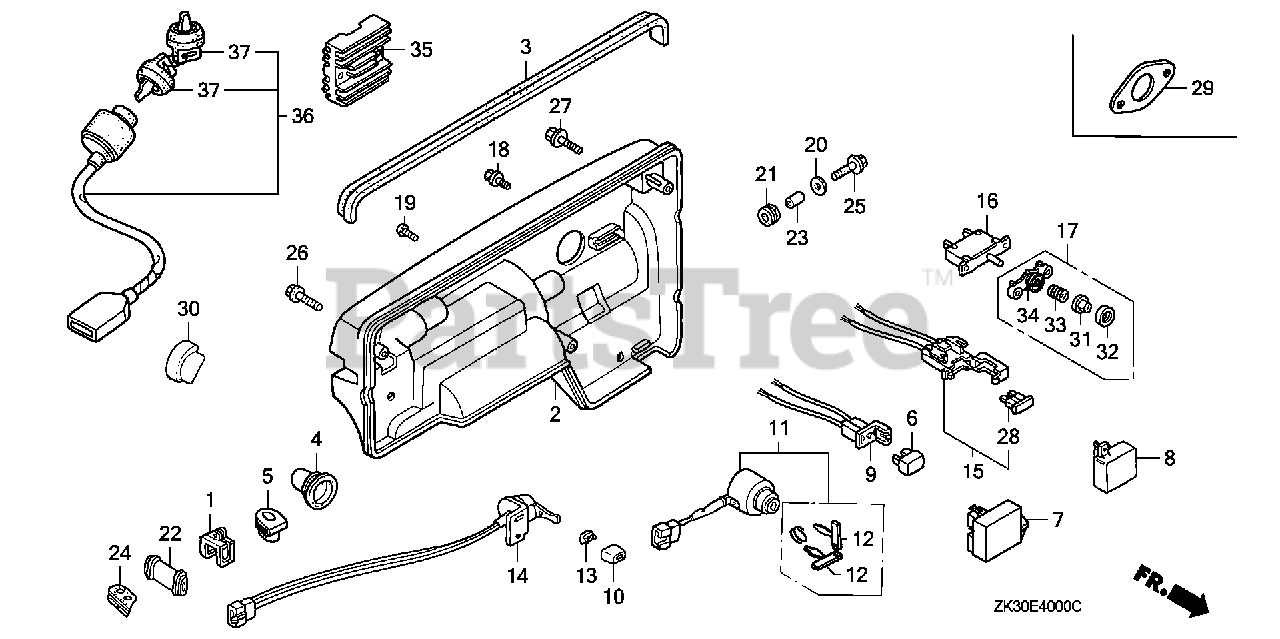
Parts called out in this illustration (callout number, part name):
1	CLIP, WIRE
2	CASE, CONTROL *R280* (POWER RED)
3	RUBBER, CONTROL
4	GROMMET, MAIN WIRE
5	GROMMET, SWITCH WIRE
10	KNOB, PETCOCK LEVER
13	BUSH, CONTROL KNOB
14	SWITCH ASSY., ENGINE STOP
19	SCREW, GLOVE BOX
20	WASHER, AIR DUCT
21	RUBBER, CONTROL BOX
22	TUBE, CORD
23	COLLAR, CONTROL BOX
24	GROMMET, TUBE
25	BOLT, FLANGE (6X18)
26	BOLT, FLANGE (6X40)
27	BOLT, FLANGE (8X20)
